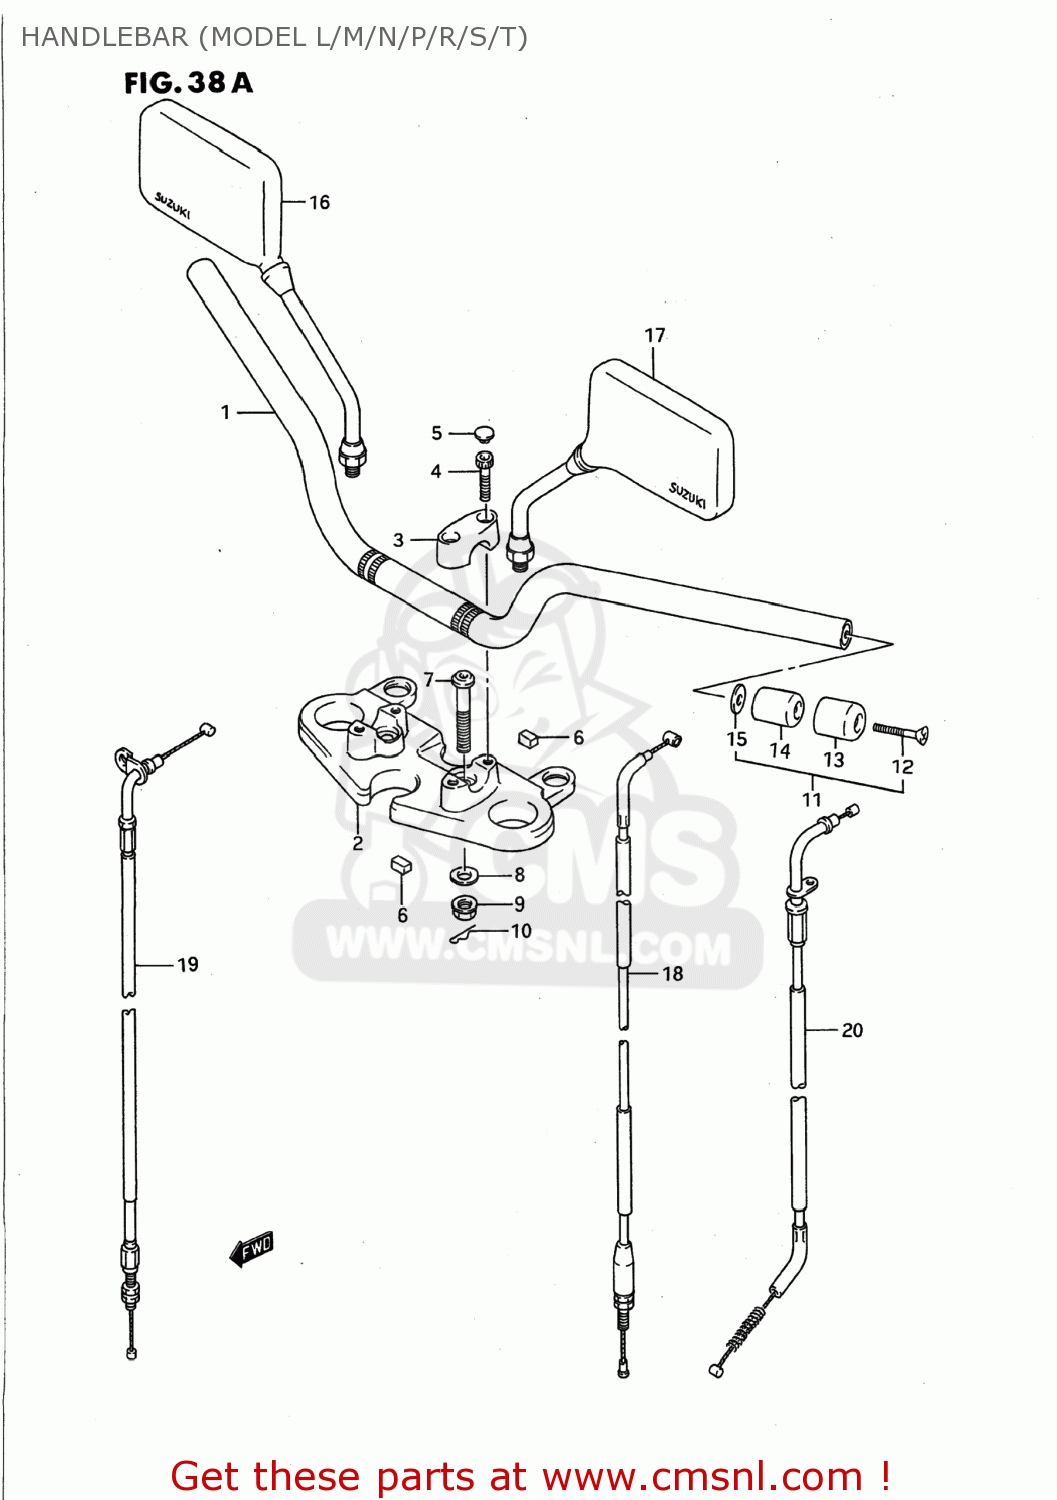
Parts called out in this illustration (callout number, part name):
1	HANDLEBAR
2	HOLDER,HANDLEBAR LWR
3	HOLDER,HANDLEBAR UPR
4	BOLT
5	CAP(OD:14.5)
6	CUSHION,HANDLE HOLDER
7	BOLT(10X66)
8	WASHER
9	NUT
10	PIN 20X20
11	BALANCER SET,HANDLEBAR
12	SCREW
13	CAP,BALANCER
14	BALANCER,HANDLEBAR
15	SPACER,BALANCER
16	MIRROR ASSY,RR VIEW,R
17	MIRROR ASSY,RR VIEW,L
18	CABLE ASSY,CLUTCH
19	CABLE ASSY,THROTTLE
20	CABLE COMP,STARTER
